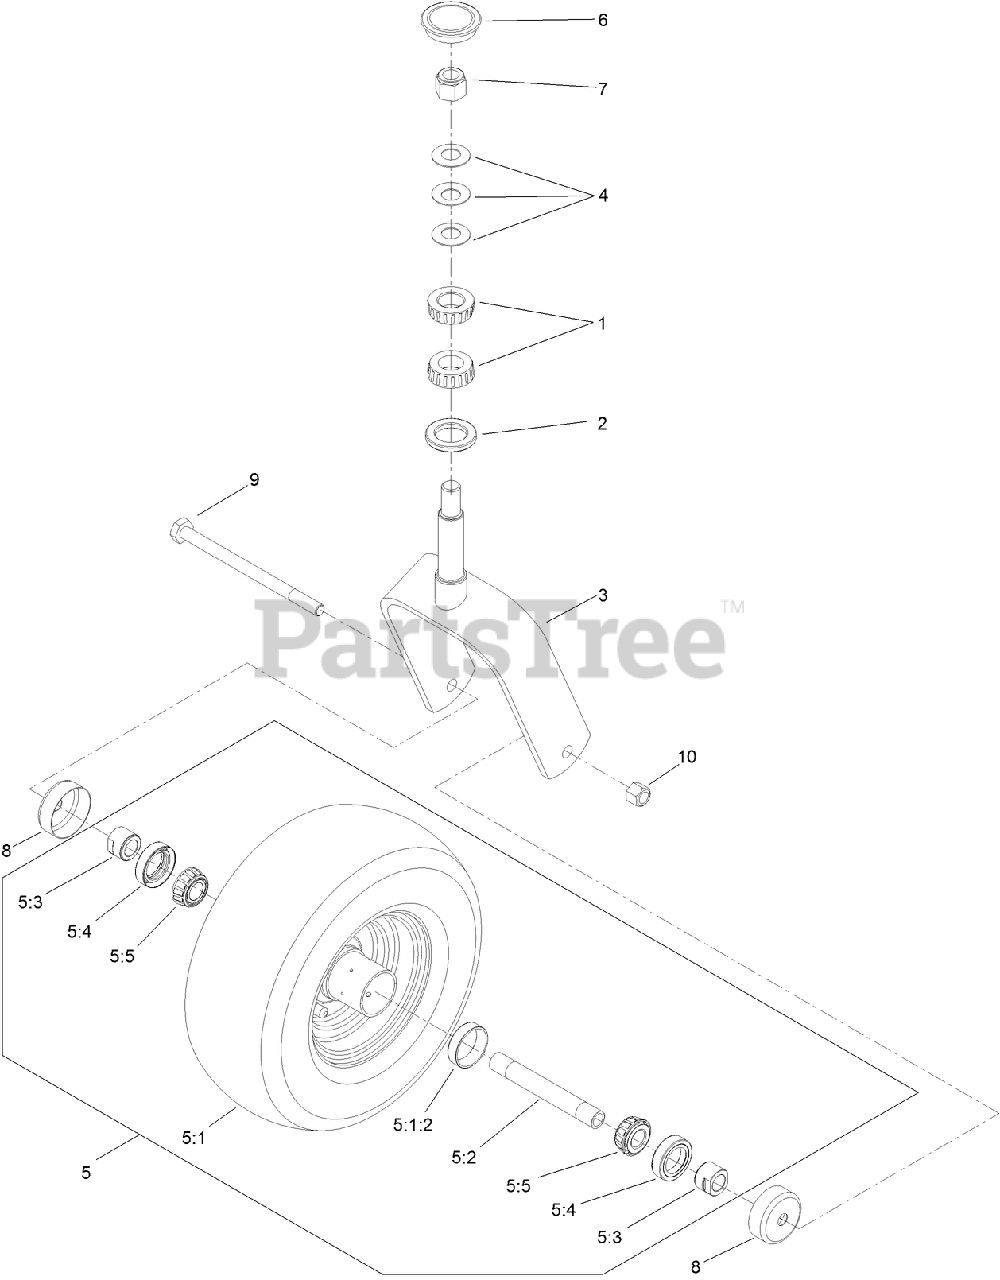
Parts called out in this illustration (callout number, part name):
1	BEARING-ROLLER, TAPERED
2	SEAL-GREASE
3	FORK-CASTER
4	WASHER-BELLVILLE
5	WHEEL AND BEARING ASM
5:1	WHEEL AND TIRE ASM
5:1:2	BEARING-CUP
5:2	AXLE-CASTER
5:3	SPACER-NUT
5:4	SEAL-CASTER
5:5	BEARING-CONE, TAPER
6	CAP-GREASE
7	NUT-LOCK, NI
8	GUARD-SEAL
9	SCREW-HH
10	NUT-LOCK, NI
